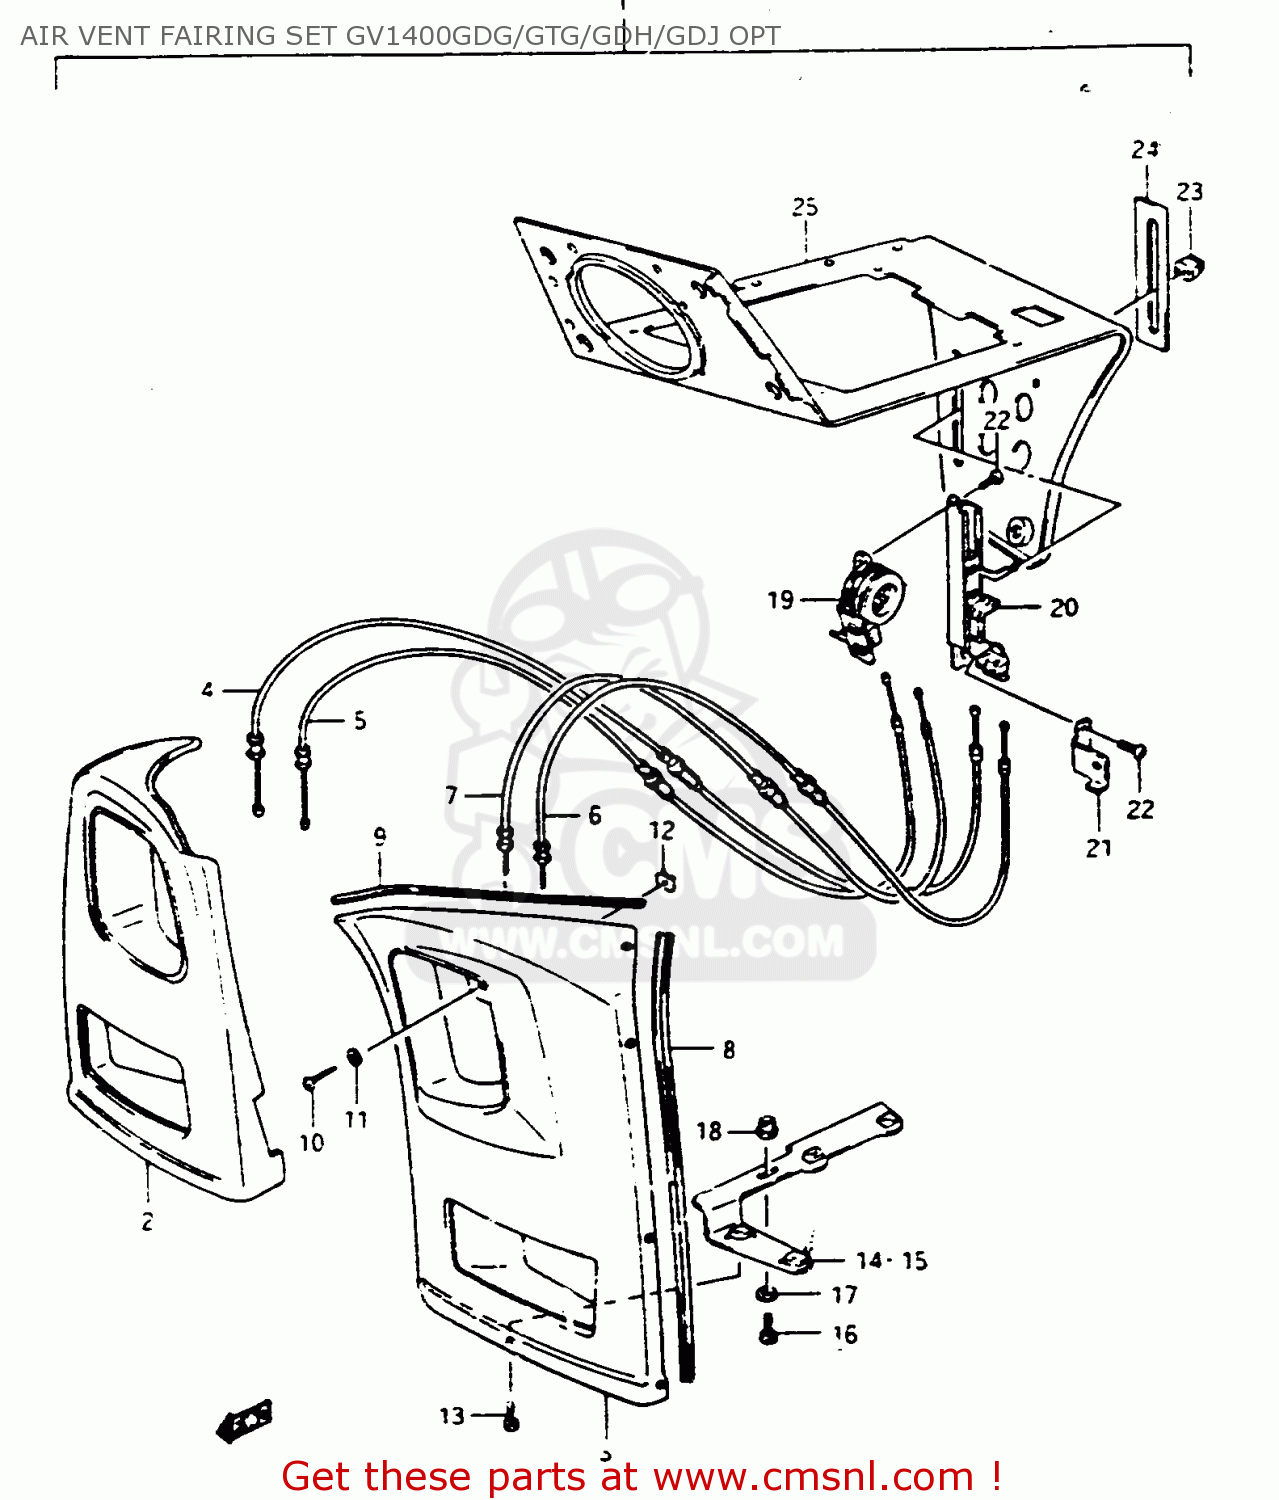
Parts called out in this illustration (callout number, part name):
1	FAIRING SET
2	FAIRING ASSEMBLY,EXTENSION
3	FAIRING ASSEMBLY,EXTENSION
4	CABLE COMP,VENTILATOR
5	CABLE COMP,VENTILATOR
6	CABLE COMP,VENTILATOR
7	CABLE COMP,VENTILATOR
8	MOLDING NO.1
9	MOLDING, NO.2
10	SCREW
11	WASHER (5.5X14X1.2)
12	NUT
13	SCREW, FRONT & REAR
14	BRACKET, EXTENSION RH
15	BRACKET,FAIRING EXTENSTION
16	BOLT 6X16
17	WASHER
18	NUT 6MM
19	GUIDE ASSEMBLY,VENTILATOR
20	OPERATION ASSEMBLY,VENTILATOR
21	BRACKET COMP,VENT OPERATING
22	SCREW
23	KNOB,VENTILATOR OPERATING
24	EMBLEM,PANEL COWLING,LEFT
25	PANEL,COWLING,LEFT
